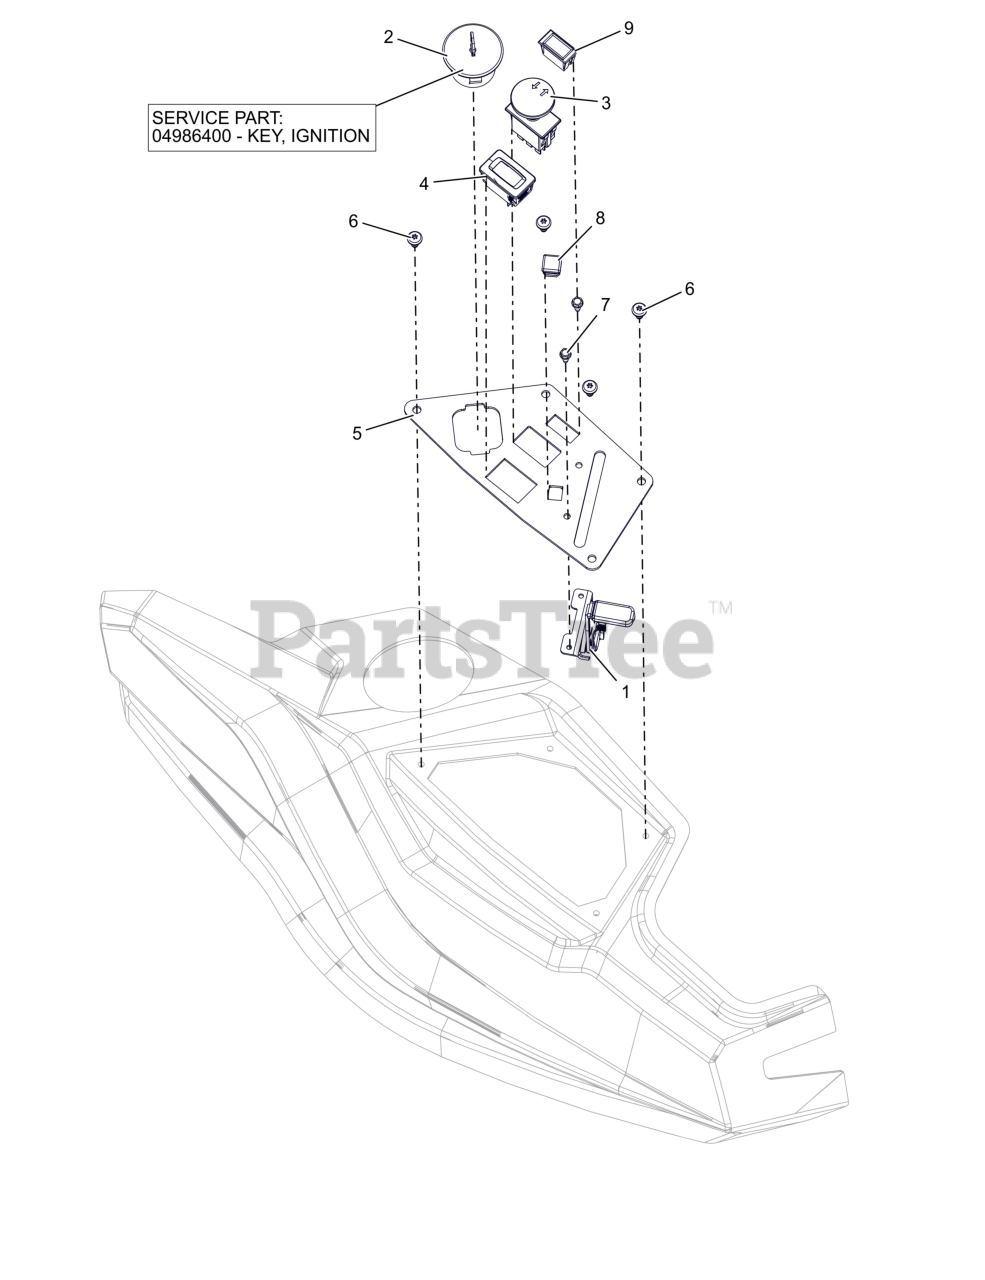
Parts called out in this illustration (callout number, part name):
1	CABLE, THROTTLE
2	KEYSWITCH-IGNITION 3 POS
2	KEY, IGNITION
3	SWITCH, CLUTCH (YELLOW)
4	HOUR METER
5	PANEL, CONTROL (ORANGE)
6	SCR-PAN .25-15X.50 6L H/LZB500
7	SCR,TAP #10-24X.50 HWH TR ZCC
8	PLUG, 5/8" SQ BLACK (14-20GA)
9	SWITCH,BLANK
